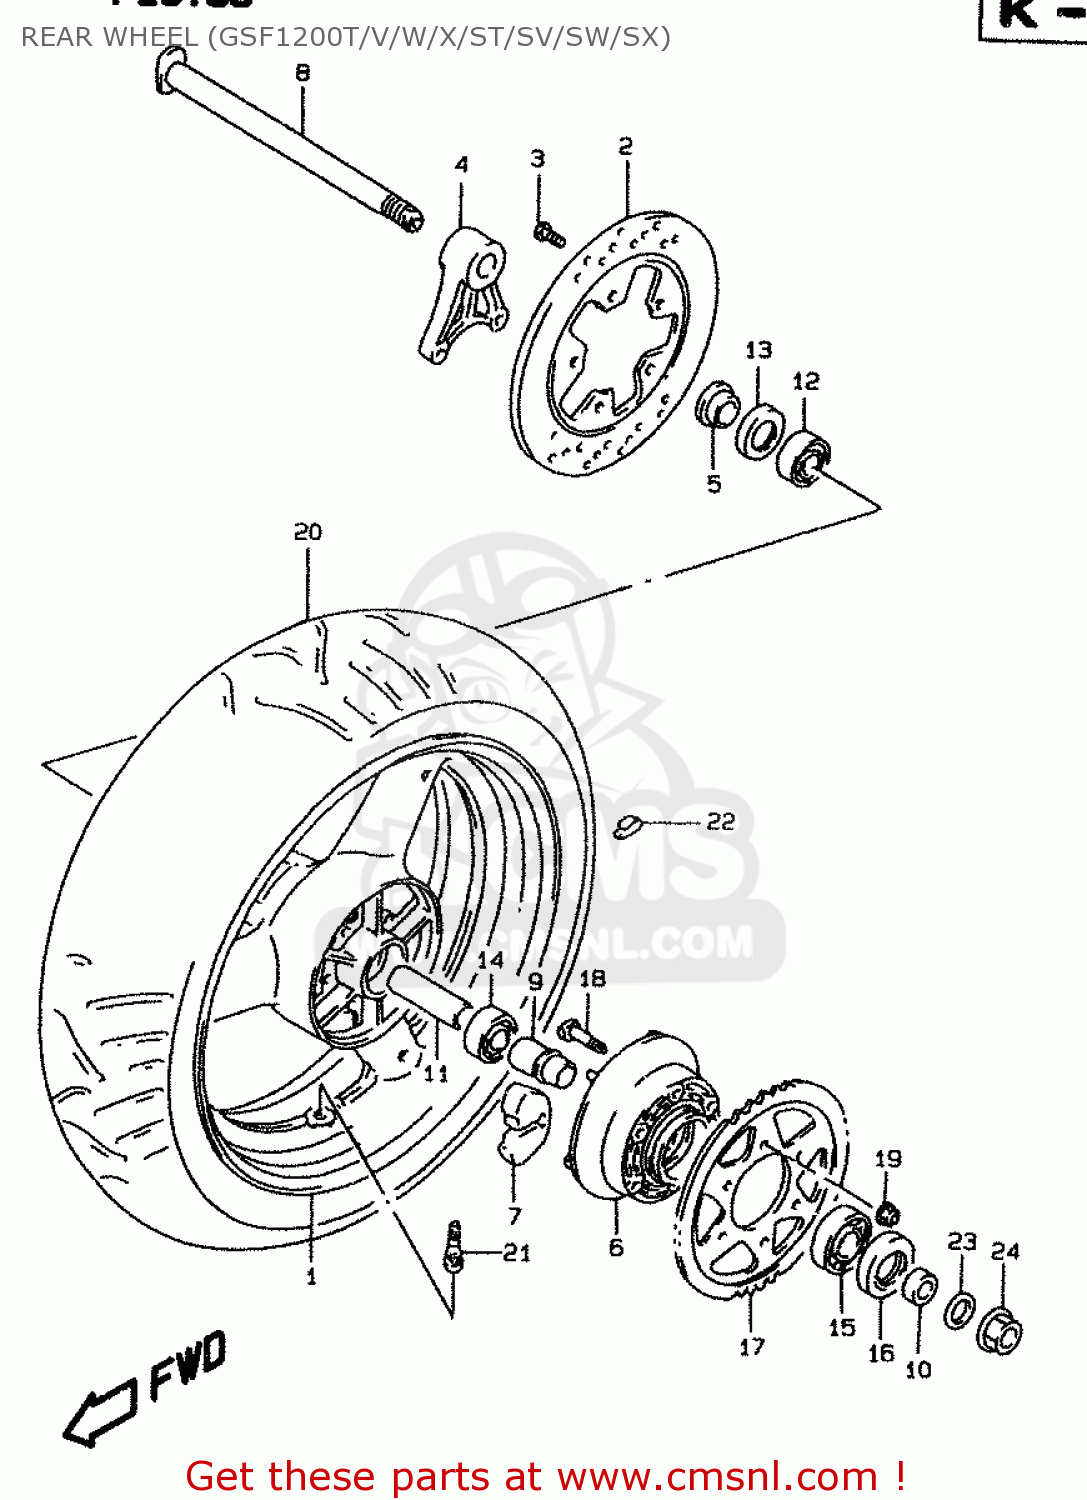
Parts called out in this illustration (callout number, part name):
1	WHEEL,REAR (MT5.50X17)(G
2	DISC,RR BRAKE
3	BOLT 8X33
4	BRACKET,RR CALIPER
5	SPACER,RR AXLE,R
6	DRUM,RR SPROCKET
7	ABSORBER,RR HUB SHOCK
8	AXLE,RR
9	RETAINER,RR HUB BEARING
10	SPACER,RR AXLE,L
11	SPACER,RR WHEEL HUB BEARING
12	BEARING(20X47X14)
13	SEAL,OIL(28X47X7)
14	BEARING(20X47X14)
15	BEARING(25X62X17)
16	SEAL,OIL(35X62X8)
17	SPROCKET,RR(NT:45-530)
18	BOLT
19	NUT
20	TIRE,RR(180/55 ZR17 73W)
21	VALVE ASSY,WHEEL RIM(TR412)
22	BALANCER,WHEEL (10G)
23	WASHER(18.5X28X2.6)
24	NUT
